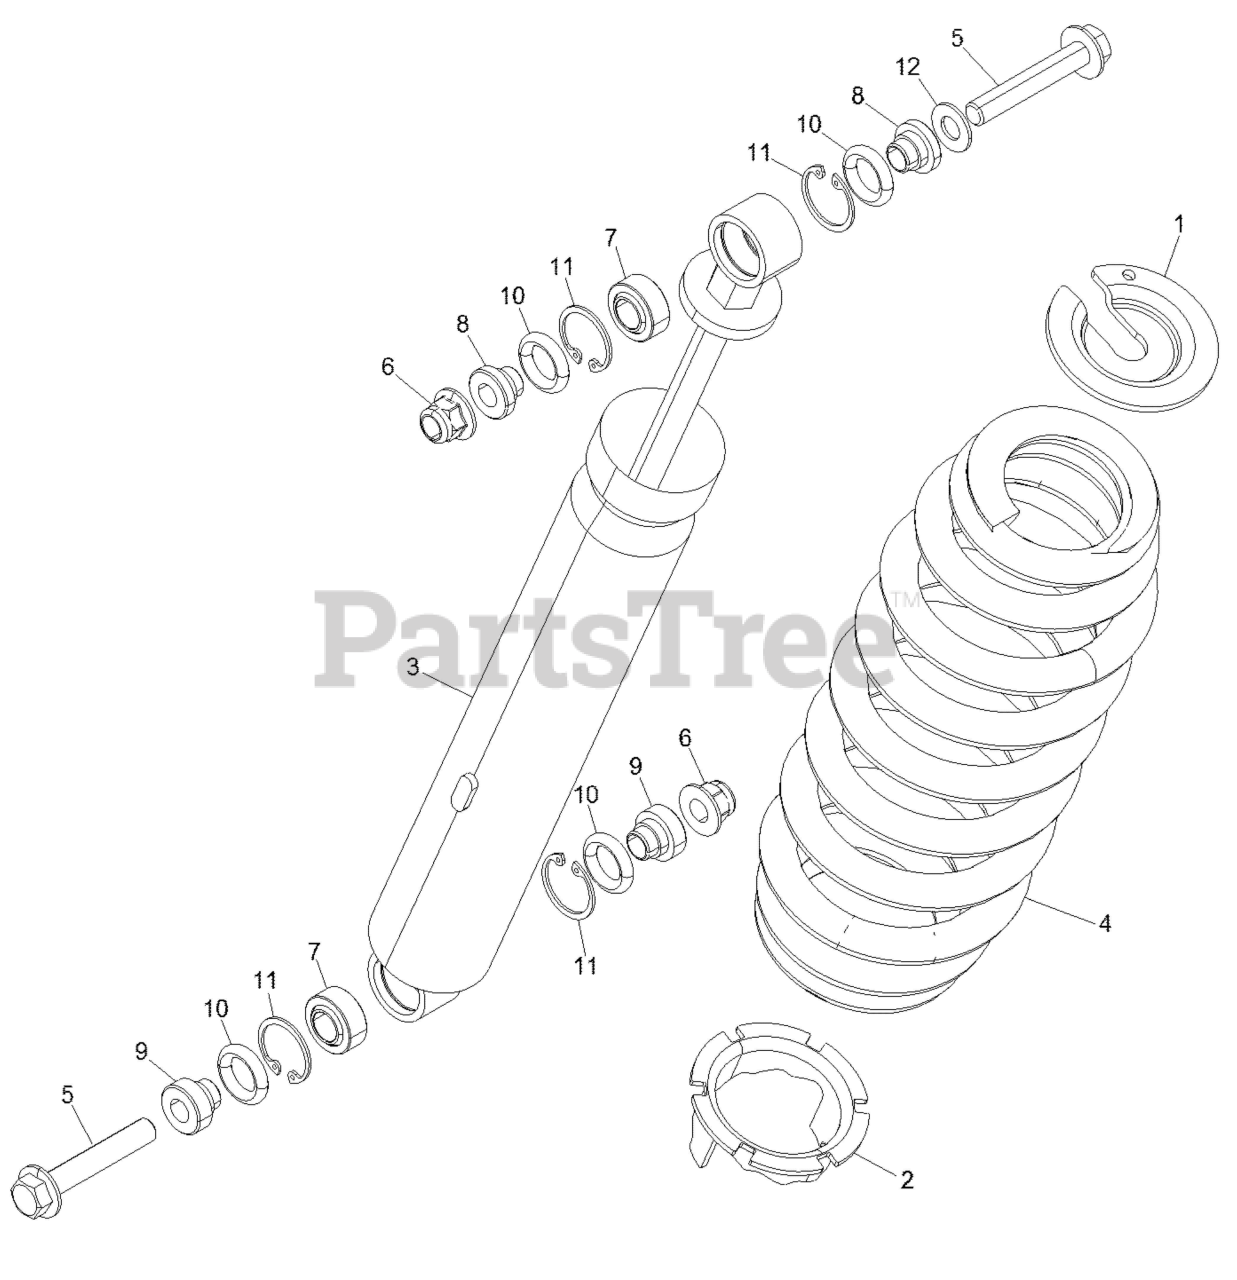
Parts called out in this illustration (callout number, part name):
1	RETAINER-SPRING,STEEL
2	CAM-ADJUSTING,SPRING,STEEL
3	SHOCK-REAR
4	SPRING-350#,M.BLK
5	SCR-HXFL-M10X1.25X60 10.9 ZOD
6	NUT-M10X1.25,FLG,NYLOC-OLIVE D
7	BEARING-SPERICAL,SHOCK
8	BUSHING-REDUCER,.500X.398,ZYW
9	BUSHING-REDUCER,.500X.398,ZYW
10	O-RING,0.600IDX.210
11	RING-RETAINING,1.00 ID
12	WASHER,3/8 FW
